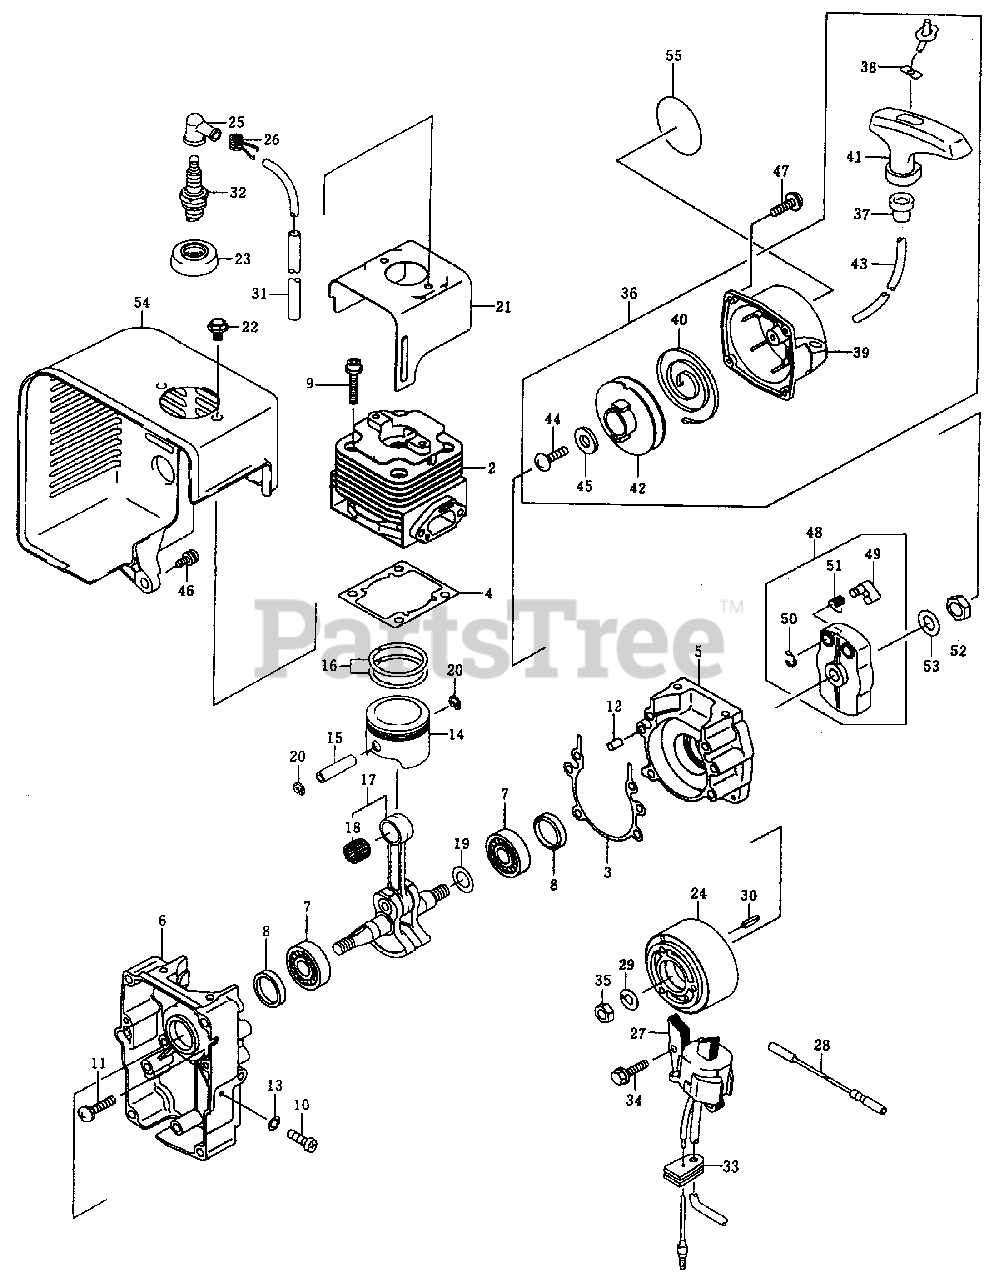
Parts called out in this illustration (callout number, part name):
2	Cylinder
5	Crankcase
6	Crankcase
8	Seal-Oil
12	Pin-Dowel
15	Piston Pin
16	Piston Ring Set
17	Crankshaft Assembly
18	Bearing-Needle
19	Shim (0.10)
20	Snap Ring
24	Flywheel
25	Spark Plug Cap
26	Terminal
27	Ignition CoilAssembly
28	Lead Wire
36	Recoil Starter
37	Rope Guide
39	Recoil Starter Case
40	Recoil Spring
48	Starting Pulley
50	Snap Ring
51	Return Spring
55	Decal-Engine
